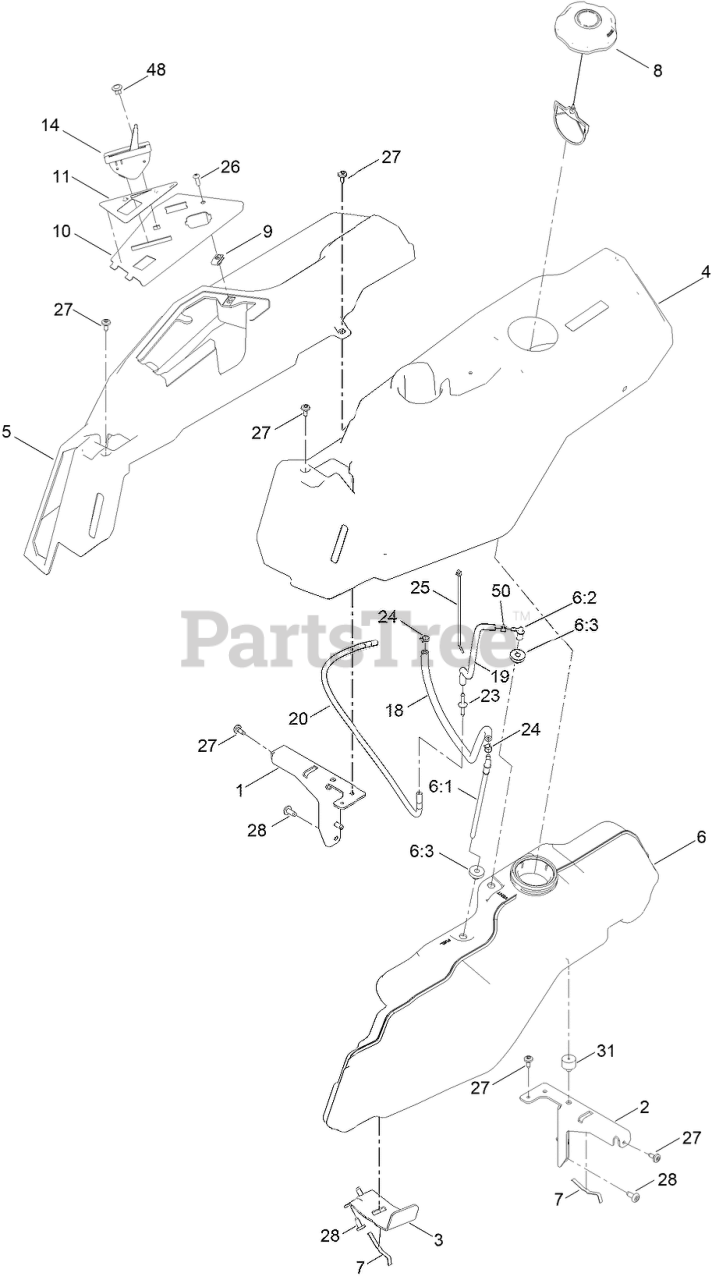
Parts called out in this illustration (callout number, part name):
1	SUPPORT-POD, RH
2	SUPPORT-POD, LH
3	SUPPORT-TANK, FUEL
4	POD-LH
5	POD-RH
6	TANK-FUEL ASM
6:1	CONNECTOR-ELBOW, 90 DEG
6:2	FITTING-ELBOW 90
6:3	BUSHING
7	SPRING
8	CAP-FUEL, RATCHETING
10	PANEL - CONTROL
11	DECAL-PANEL CONTROL
14	CABLE-THROTTLE AND CHOKE
18	HOSE-FUEL
19	HOSE-FUEL
20	HOSE-VENT
23	ADAPTER ORIFICE
24	CLAMP-HOSE
25	TIE-CABLE
26	SCREW-PRH
27	SCREW-SHOULDER
31	BUMPER-GROMMET
48	PLUG-DASH
50	CLAMP-HOSE
